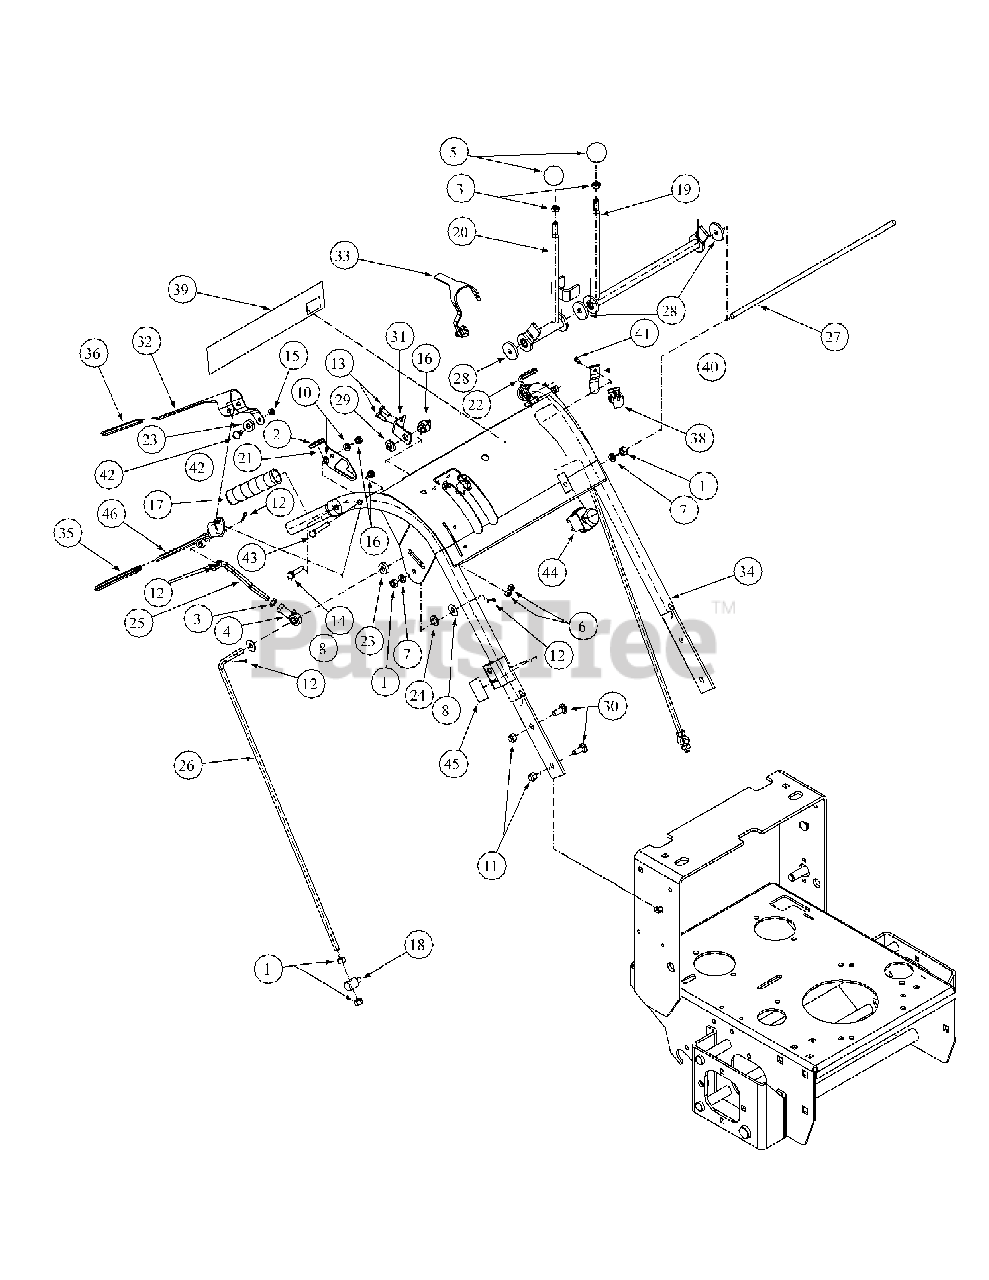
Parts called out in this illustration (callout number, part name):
1	Hex Nut, 3/8-16
2	Grip, Neutral Latch, 1.25", Black
3	Hex Nut, Jam 3/8-24
4	End Rod, 3/8 Female
5	Knob, 1-3/8 x 1-19/64, 3/8-24
6	Lock Nut, Nylon Insert, 1/4-20
7	Lock Washer, 3/8
8	Flat Washer, 3/8
10	Flat Washer, 5/16
11	Lock Nut, Nylon Insert, 3/8-16
12	Cotter Pin, 3/32 x 1/2
13	HHCS, 1/4-20, .75
14	HHCS, Standard, 5/16 -18 x 2
15	Lock Nut, SS, Nylon Insert, 1/4-28
16	Operator Presence Switch
17	Grip, 4-5/8, Black, Plastic Handle
18	Pivot Belt Tightener
19	Control Assembly, Speed, Hydro LH
20	Control Assembly, Speed, Hydro RH
21	Latch, RH Neutral Hydro
22	Latch, LH Neutral Hydro
23	Hydro Spacer Control Rod
24	Hydro Bushing Control Rod
25	Control Rod Short Hydro
26	Control Rod Long Hydro
27	Hydro Rod Speed Control
28	Friction Washer
29	Hex Nut, Dead Man Switch
30	Carriage Bolt, 3/8-16 x 2
31	Neutral Safety Mounting Switch
32	Operator's Presence Control, RH
33	Operator's Presence Control, LH
34	Hydro Handle Assembly
35	Control Sleeve, Black
36	Operator's Presence Sleeve, Yellow
37	Harness Assembly Adapter
38	Snap Mounting Switch
39	Label Handle
40	Retension Spring
41	Screw, TT, 10-24, .500, HXINDWSH
42	Shoulder Screw, .38 x .412, 1/4-28
43	HHCS, 5/16-18, 2.00
44	Switch, Electric PTO
45	Decal, Parking Brake
46	Control Lever Assembly
